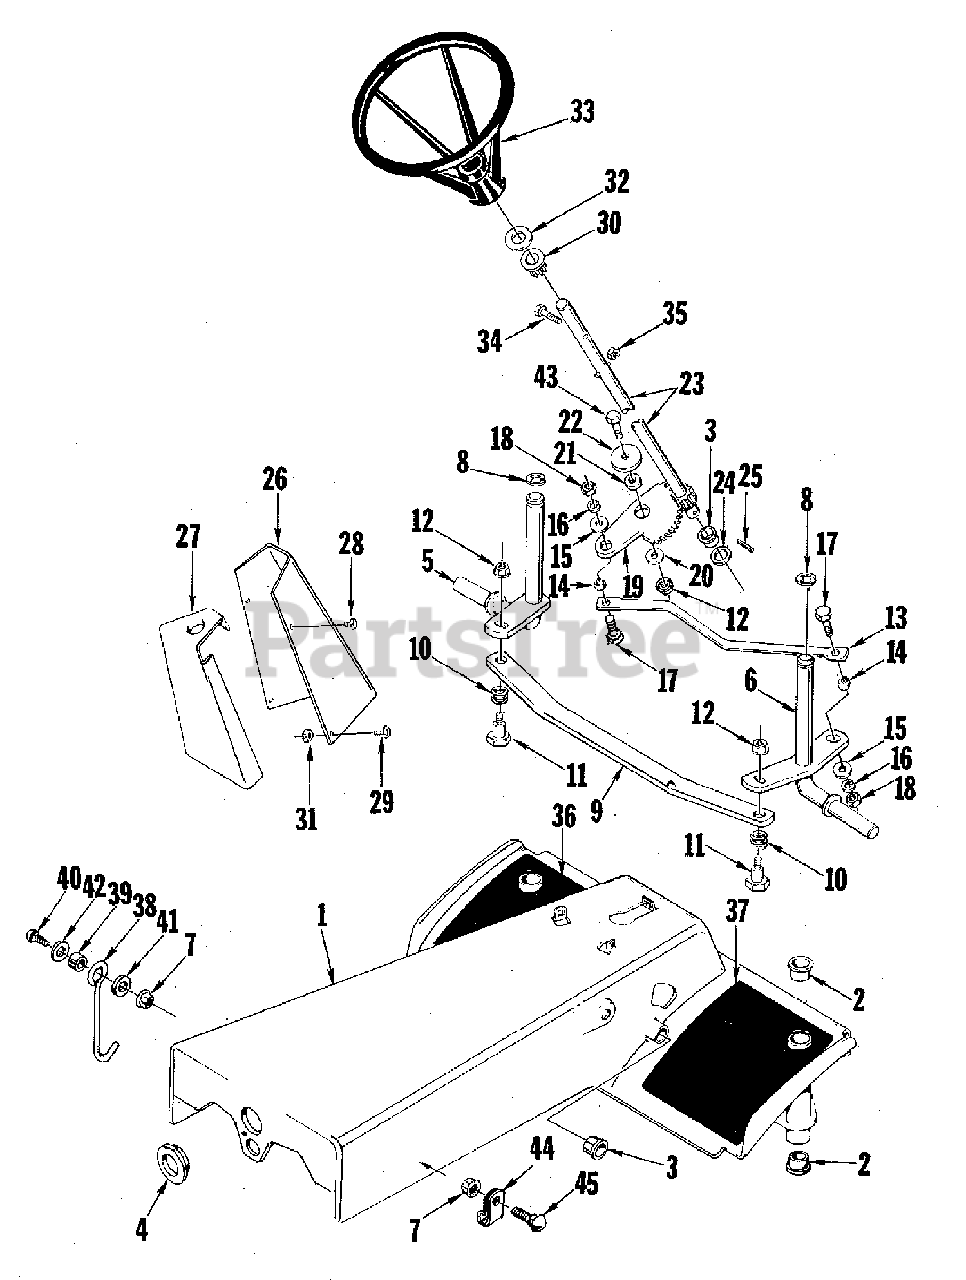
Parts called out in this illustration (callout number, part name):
1	FRAME FRONT ASSEMBLY
4	BUSHING, Pivot
7	NUT, Flange, 5/16-18
8	RING, Retaining
11	BOLT, Shoulder
12	NUT, Flange, 3/8-26
15	WASHER, Plain, 5/16
16	WASHER, Lock, 3/8
17	SCREW, Hex, 3/8-16 x 1-1/4
18	NUT, Hex Full, 3/8-16
19	GEAR, Steering
22	WASHER, Special
23	SHAFT, Steering
25	PIN, Cotter, 1/8 x 1-1/4
26	SUPPORT, Steering
28	SCREW, Self Tapping, 10 x 1/2
29	SCREW, Flange Head, 1/4-20 x 3/4
31	NUT, Retainer, #20-4
33	WHEEL, Steering
34	SCREW, Hex, 5/16-18 x 1-1/4
35	NUT, Hex Full Lock, 5/16-18
38	HOOK, Transport
40	BOLT, Carriage, 5/16-18
43	SCREW, Hex Cap, 3/8-16 x 1-1/4
45	BOLT, Carriage, 5/16-18 x 1/2
